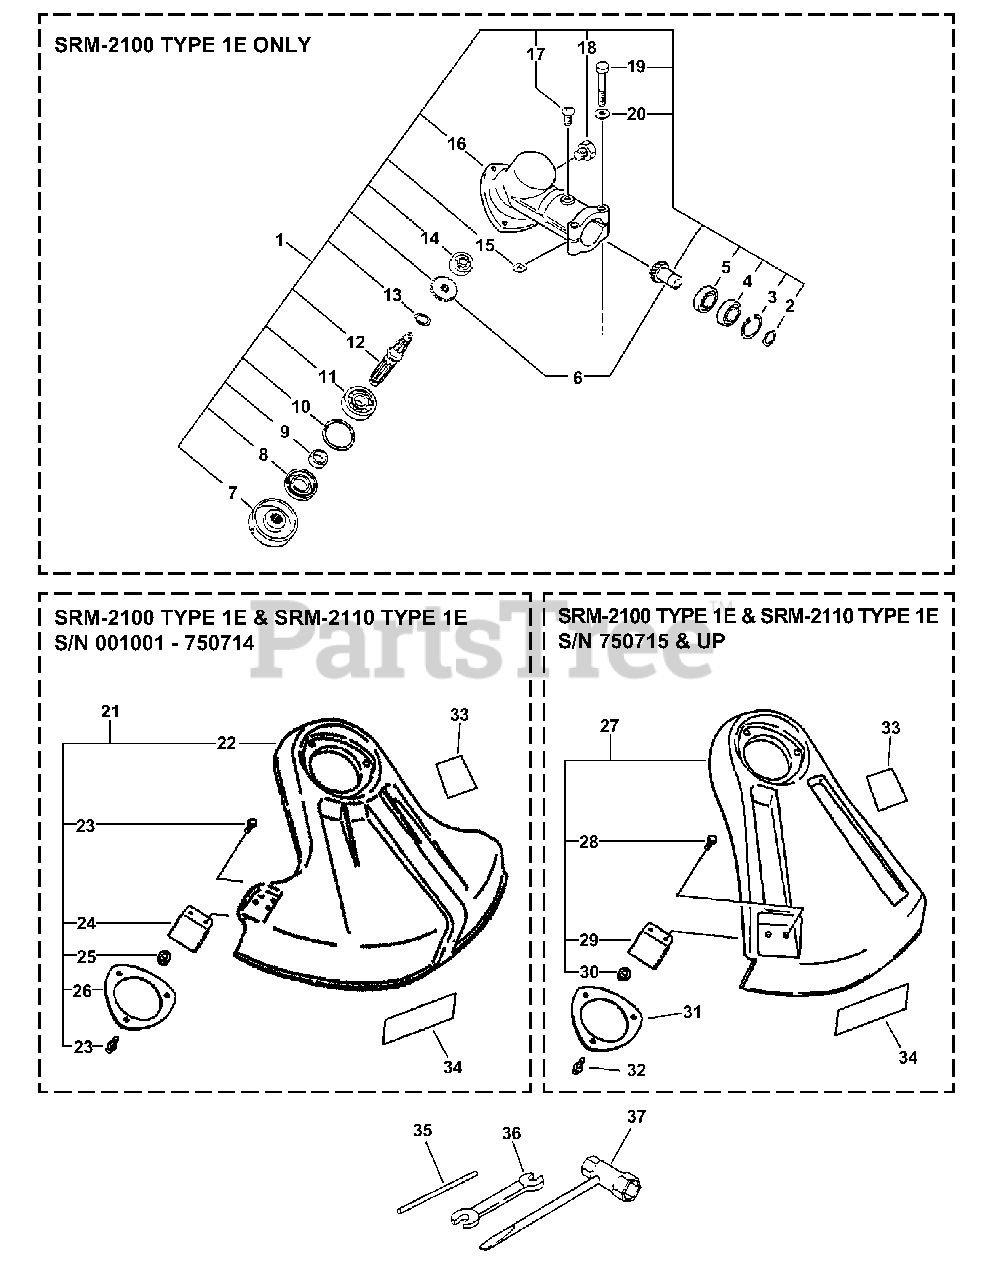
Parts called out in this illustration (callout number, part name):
1	GEAR CASE ASSY
2	RING, RETAINING - 10
3	RING, RETAINING - 22
4	BEARING, BALL - 6900Z
5	BEARING, BALL - 6900
6	GEAR SET - BEVEL
7	ADAPTOR, BLADE - UPPER
8	SEAL, OIL
9	SPACER
10	RING, RETAINING - 32
11	BEARING, BALL - 6201
12	GEAR - SHAFT
13	RING, RETAINING - 12
14	BEARING, BALL - 609
15	SHIM
16	CASE, GEAR
17	SCREW - 5X10
18	BOLT - 8X8
19	BOLT - 5X35
20	WASHER - 5
21	DEBRIS SHIELD KIT
22	SHIELD, DEBRIS - PLASTIC
23	SCREW - 5X16
24	KNIFE, TRIMMER LINE
25	NUT - 5
26	PLATE, SHIELD
27	DEBRIS SHIELD KIT
28	SCREW - 5X16
29	KNIFE, TRIMMER LINE
30	NUT - 5
31	PLATE, SHIELD
32	SCREW - 5X16
33	LABEL - CAUTION
34	LABEL - ECHO
35	LOCKING TOOL
36	SPANNER - 8X10mm
37	T-WRENCH - 17X19mm
